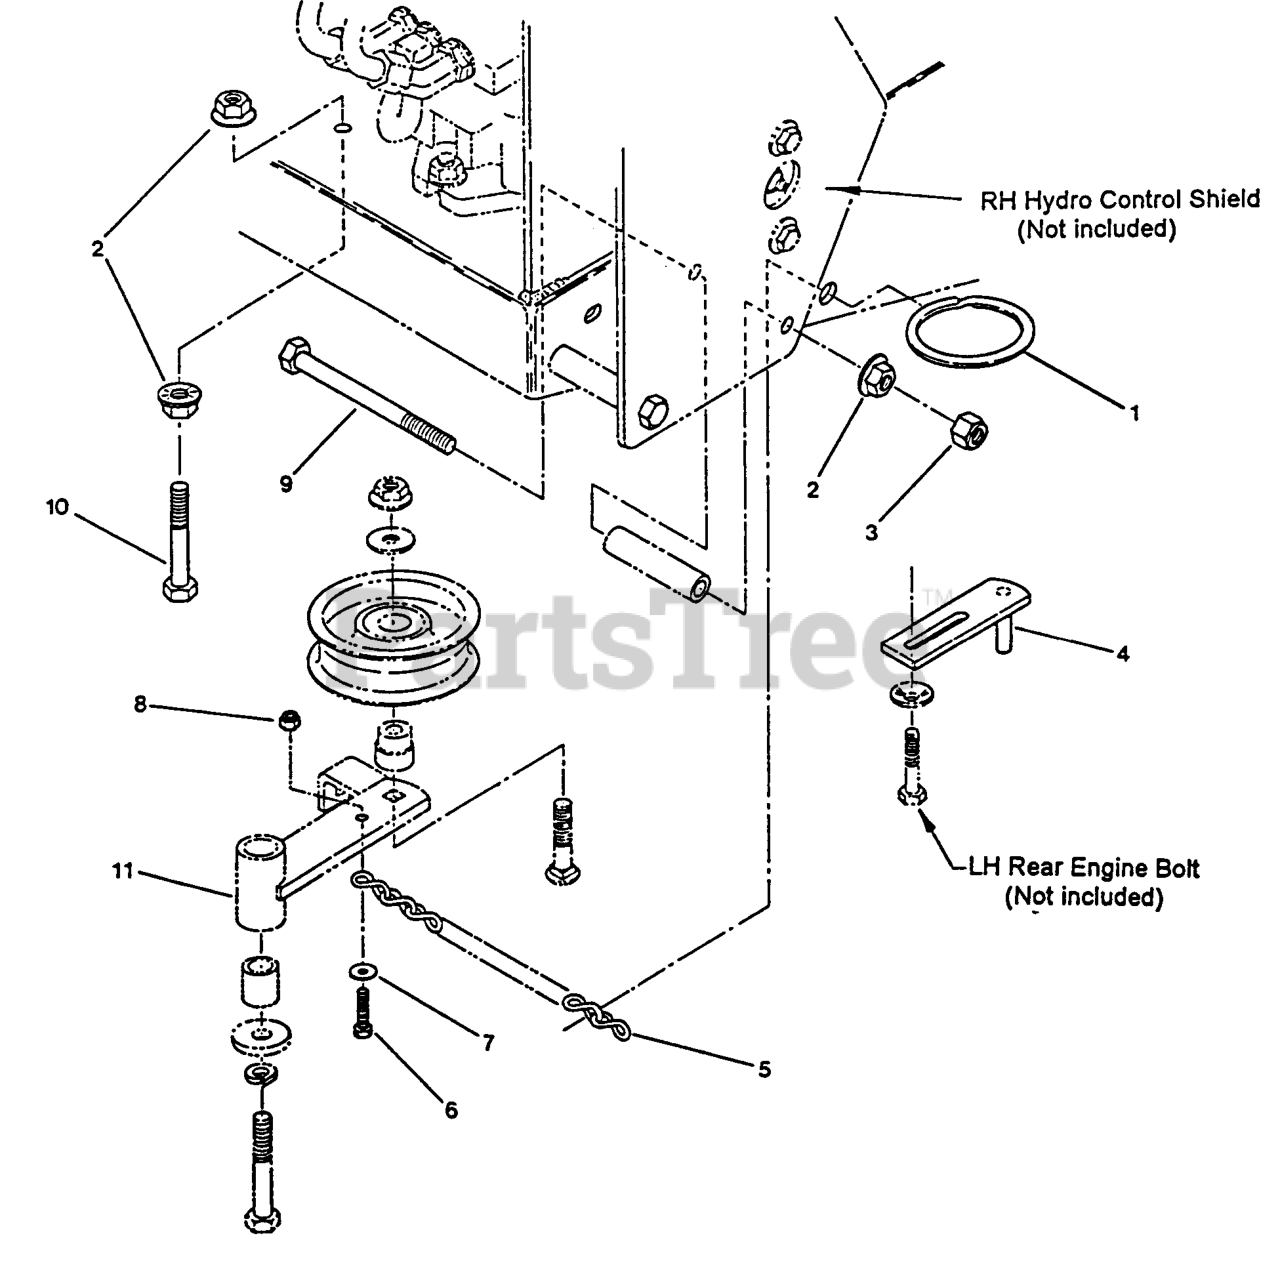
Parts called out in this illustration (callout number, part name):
1	RING-SPLIT
4	GUIDE-BELT
5	CHAIN-LINK, TWIST
6	SCREW-HSH
